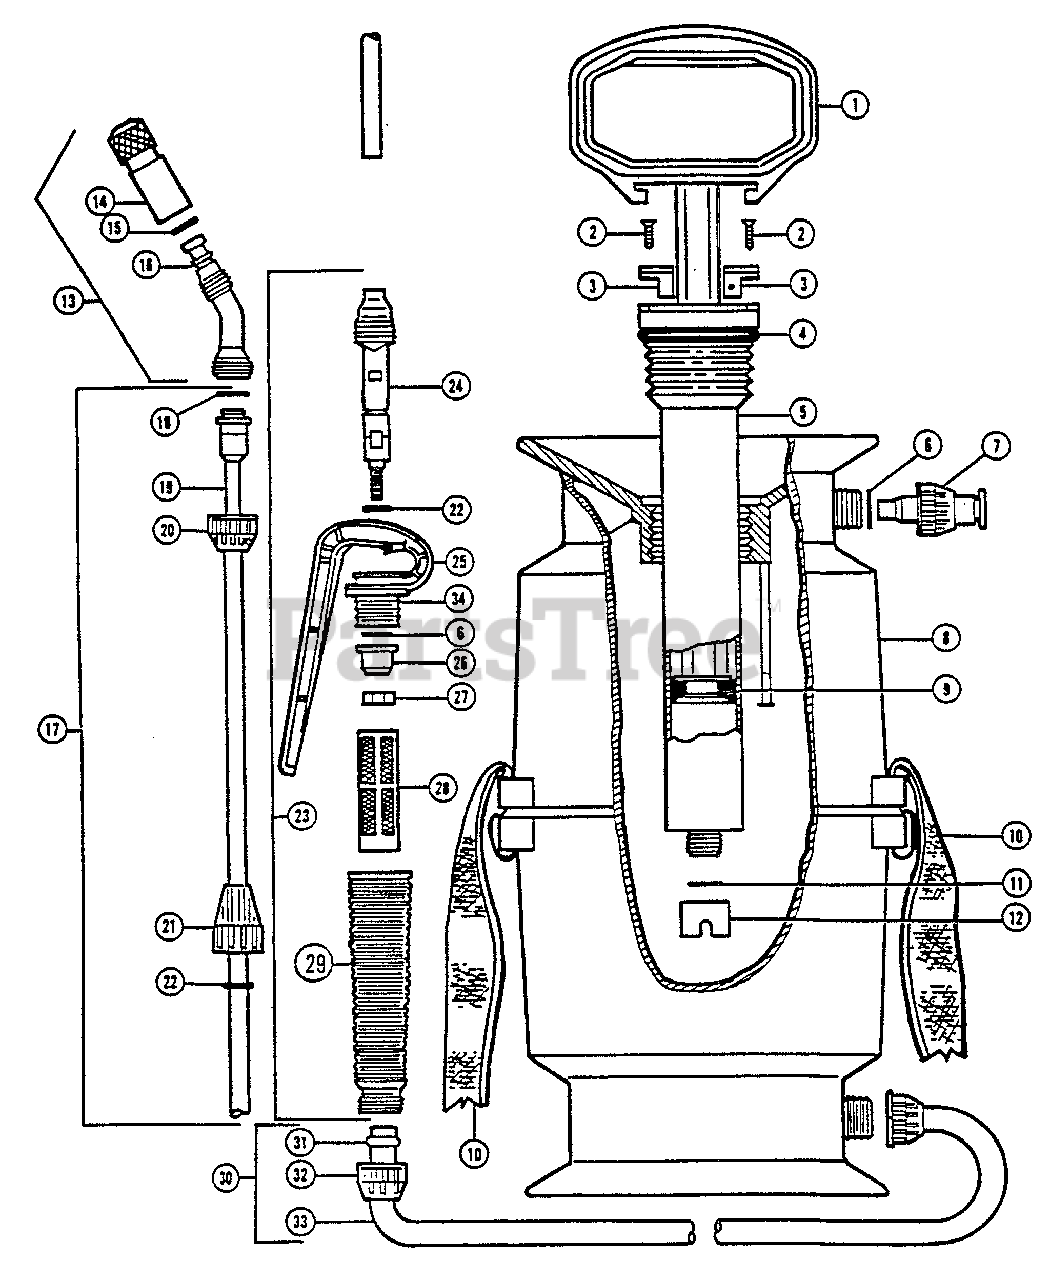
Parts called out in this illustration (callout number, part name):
2	SCREW - 7 X 7/8"
3	COVER, CHAMBER
4	O-RING - 30
5	CHAMBER MS-9, 12
6	O-RING - 8
6A	O-RING - 8
7	PRESSURE RELEASE VALVE
8	TANK -- MS-9
8A	TANK -- MS-12
9A	COLLAR SEAL, VITON
10	STRAP
12	NUT
12	WAND ASSY
13	NOZZLE ASSY
14	NOZZLE - 1mm
15	O-RING - 5
15A	O-RING - 5
16	SPRAYER
17	TUBE ASSY
18	WASHER
19	WAND TUBE
21	WAND NUT
22	O-RING - 6
22A	O-RING - 6
23	HANDLE ASSY
24	WAND SHAFT
25	BODY, HANDLE
27	NUT - 6
28	FILTER, WAND
30	HOSE ASSY
31	HOSE CAP
33	HOSE - 6 x 1.3M
34	O-RING
